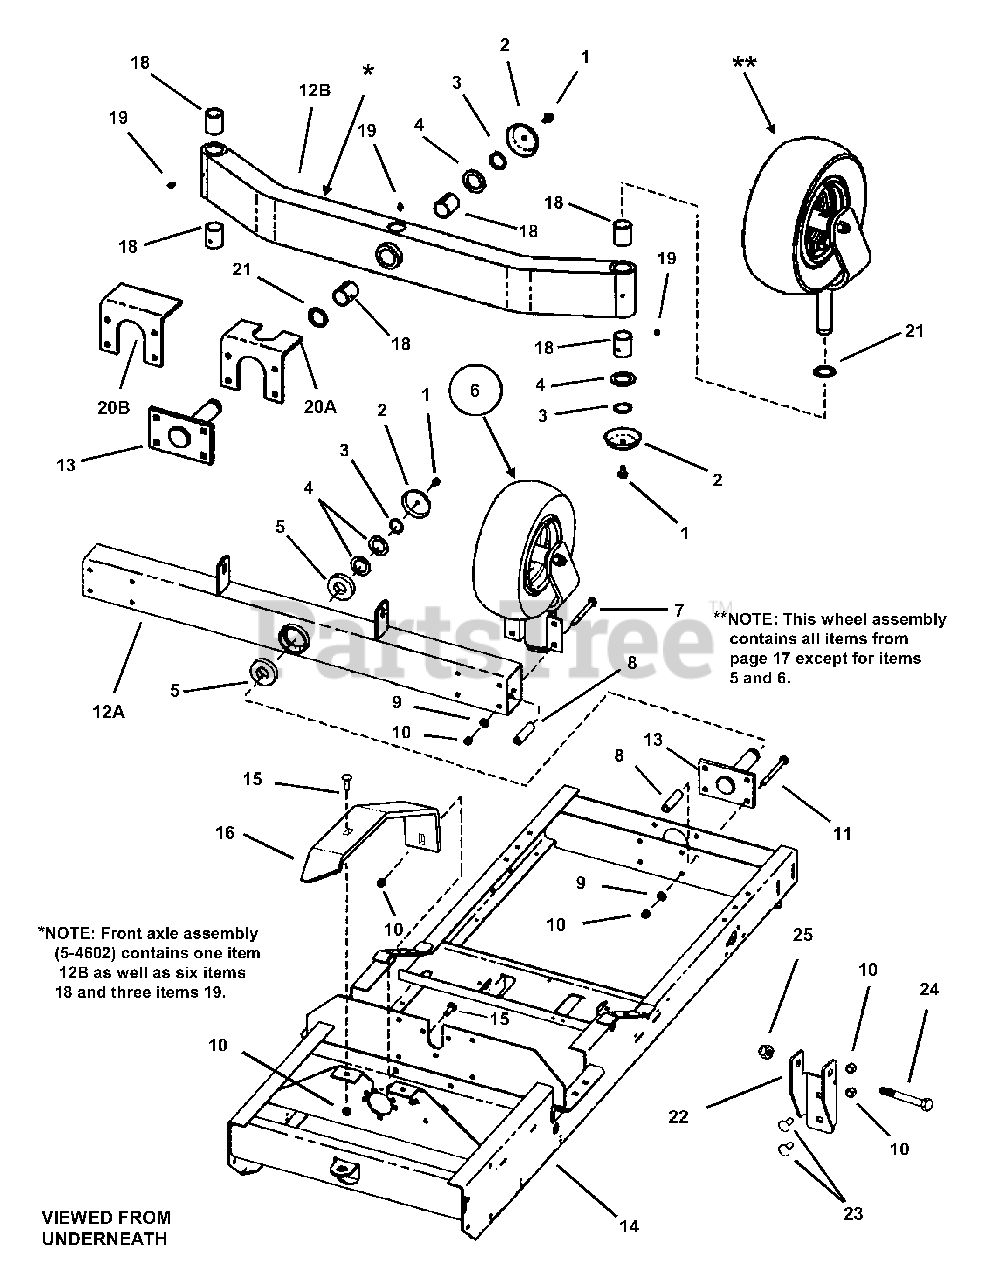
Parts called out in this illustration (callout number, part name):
1	SCREW, 5/16-18 x 5/8" Hex Flange Self Tap
2	CAP, Caster Shaft
3	RING, 1-3/16" External Retaining
4	WASHER, 1-1/4" I.D. x 1-7/8" O.D. Flat
5	BEARING, 30 mm x 62 mm
6	CASTER WHEEL
7	BOLT, 3/8-16 x 4", Carriage Short Neck Grade 5
8	TUBE, 3/4" x 5/32" x 2-45/64"
9	WASHER, 3/8" Flat
10	NUT, 3/8-16 HEX NYLON LOCK
11	BOLT, 3/8-16 x 4-1/4" Carriage Short Neck Grade 5
12A	WELDMENT, Front Axle (straight)
12B	WELDMENT, Front Axle (Wide Stance)
13	WELDMENT, Front Axle Pivot
14	FRAME, Lower (Models MZ2200K,ZM2500K)
15	BOLT, 3/8-16 x 1-1/4" Carriage Short Neck Gr. 5
16	GUARD, Skid
18	BUSHING, DX
19	LUBE FITTING, Straight (press-fit for .187 dia. Hole)
20A	BRACKET, Axle Stop (Wide Stance Caster)
20B	BRACKET, Axle Stop (Wide Stance Caster)
21	WASHER, 1-3/16" Flat
22	BRACKET, Frame Stabilizer Bar
23	BOLT, 3/8-16 x 1" Square Neck Carriage
24	BOLT, 1/2-13 x 3-3/4" Hex Head Cap, Grade 5
25	NUT, 1/2-13 HEX NYLON LOCK
